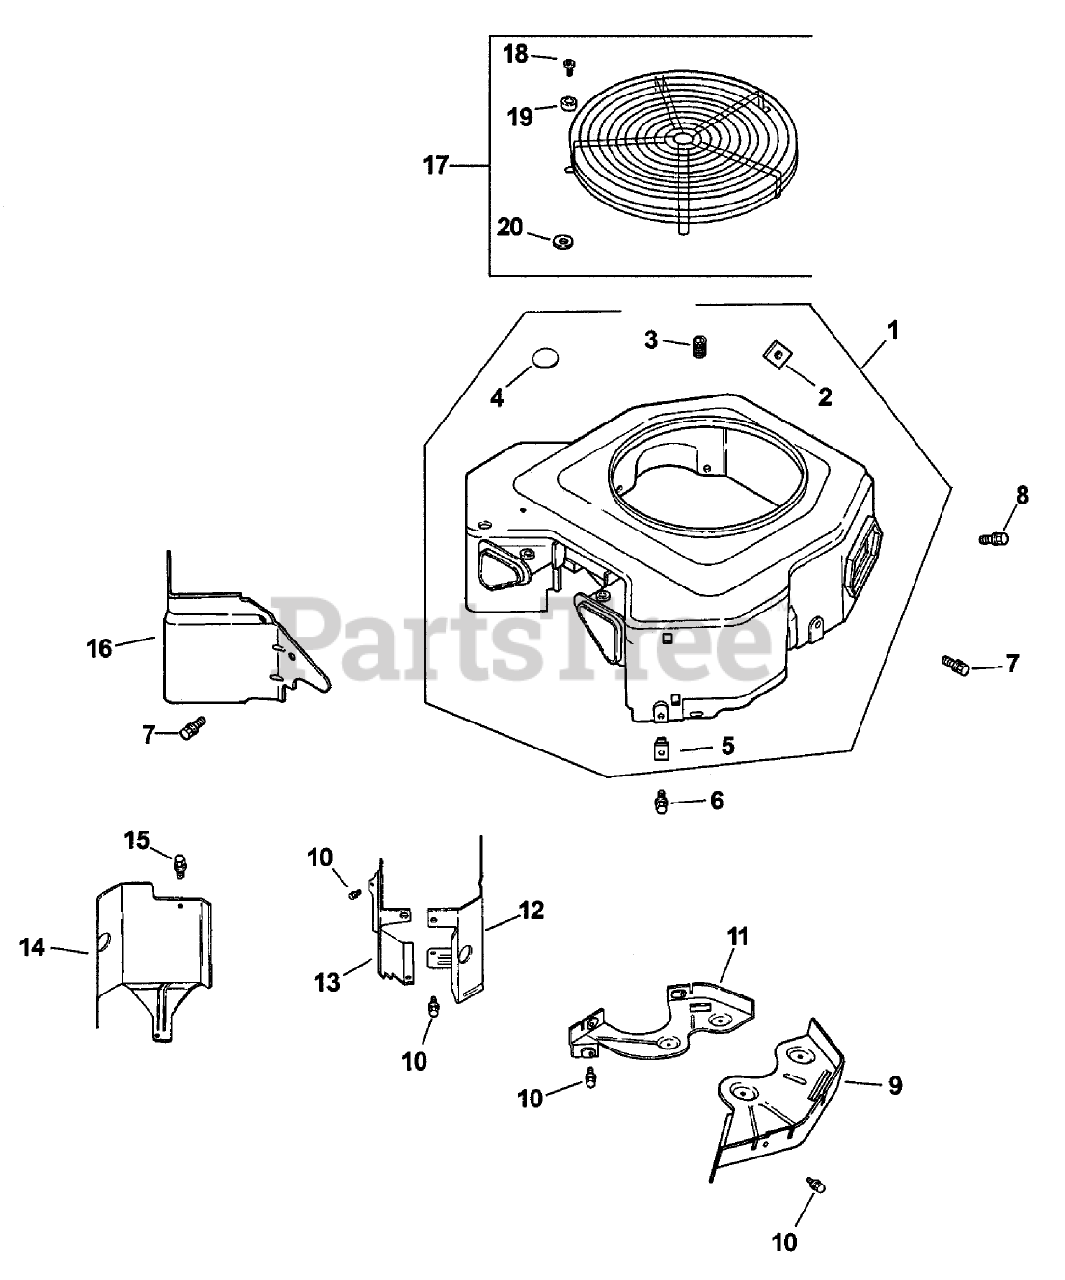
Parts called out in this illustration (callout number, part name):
1	Housing, blower (Includes 2-5)
2	Nut-Plastic
3	Screw-Set (10-24X.25)
4	PLUG-BUTTON (9/16)
5	NUT-PLASTIC
6	Screw, hex. flange
7	Screw, hex. flange
8	Screw
9	Plate-Backing (No. 2 Side)
10	Screw
11	Plate-Backing (No. 1 Side)
12	Baffle-Barrel, Cylinder (No. 2 Side)
13	Baffle, valley-#1 side
14	Baffle, cyl. barrel-#1
15	Screw
16	Baffle, valley-#2 side
17	Kit, guard (Includes 18-20, Threaded insert Qty. 3] 24 332 01)
18	Screw-Head, Pan
19	Spacer
20	Washer-plain (1/4)
